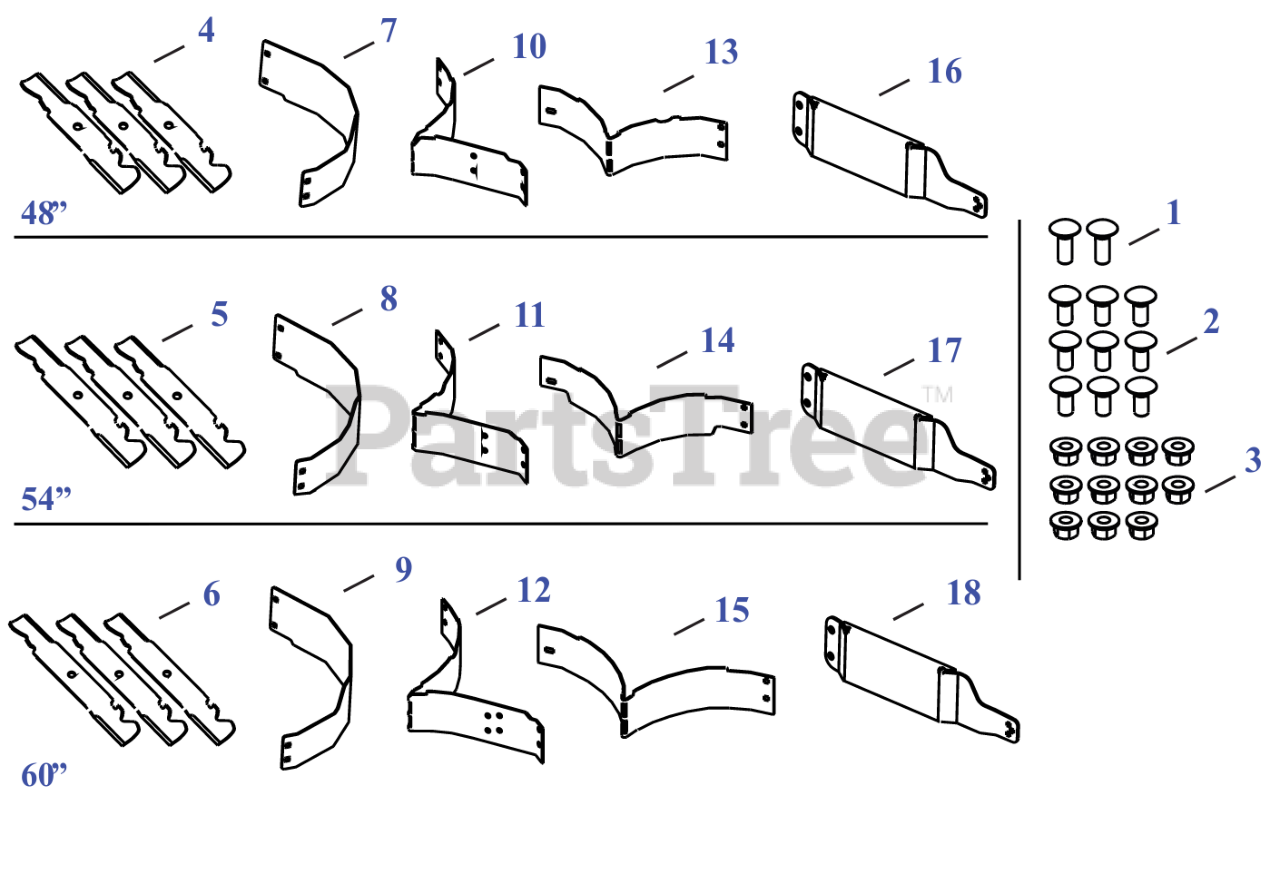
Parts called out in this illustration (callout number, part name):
1	CARRIAGE BOLT 3/8-16 x 1.00 GR5
2	CARRIAGE BOLT 3/8-16 x .75
3	FLANGE LOCK NUT
4	17" XTREME BLADE (48" DECK)
5	19" XTREME BLADE
6	21" XTREME BLADE
11	MULCH BAFFLE (CENTER)
12	60" MULCH BAFFLE (CENTER)(POWDER BLACK)
13	MULCH BAFFLE (LEFT)
14	MULCH BAFFLE (LEFT)
15	MULCH BAFFLE (LEFT)
16	PLT:DSCHRG:BLCK:48
17	BLOCKER PLATE 54"
18	BLOCKER PLATE 60"
48	PRO Z 48" MULCH KIT
54	PRO Z 54" MULCH KIT
60	PRO Z 60" MULCH KIT
